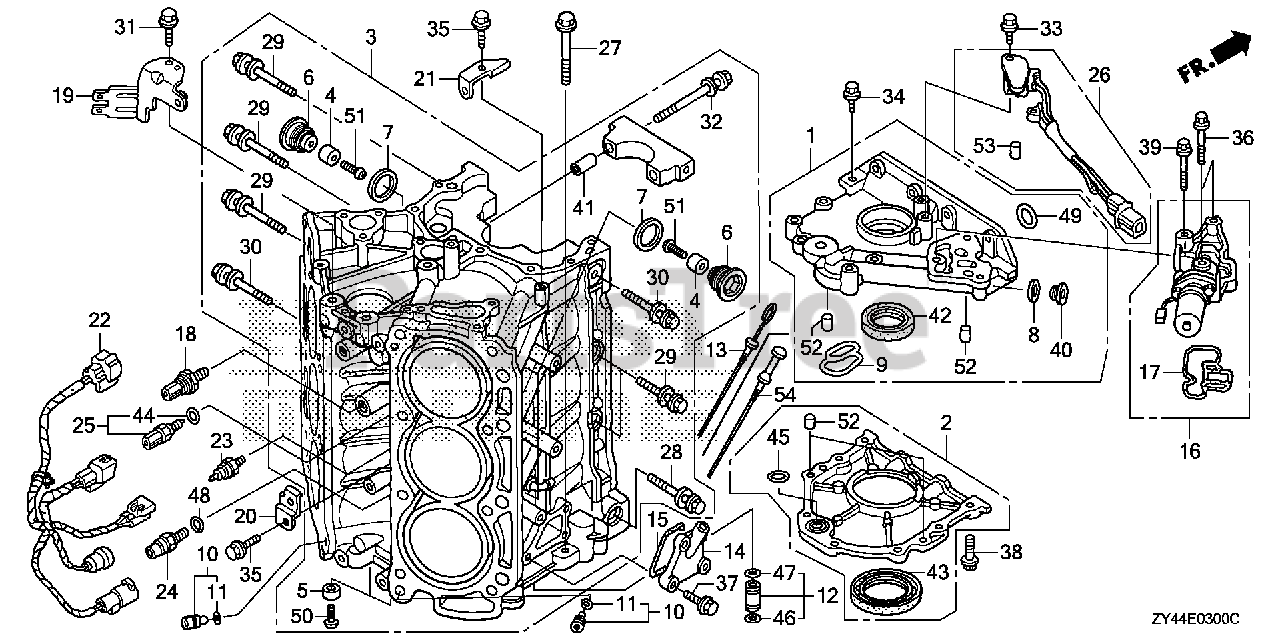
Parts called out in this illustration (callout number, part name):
1	COVER ASSY., CRANKCASE (UPPER) *NH8* (DARK GRAY)
2	CASE ASSY., OIL SEAL
3	BLOCK ASSY., CYLINDER *NH8* (DARK GRAY)
4	METAL, ANODE
5	METAL, ANODE
6	BOLT, SEALING (22MM)
7	WASHER, SEALING (22MM)
8	WASHER, SEALING (22MM)
9	GASKET, OIL HOLE
10	ORIFICE ASSY., OIL CONTROL
11	O-RING (8.8X2.4)
12	JOINT ASSY., OIL PIPE
13	DIPSTICK, OIL
14	COVER, OIL LEVEL GAUGE
15	GASKET, OIL LEVEL GAUGE
16	VALVE ASSY., SPOOL *NH8* (DARK GRAY)
17	FILTER ASSY., SPOOL VALVE
18	SENSOR, KNOCK
19	BRACKET, CONNECTOR D
20	BRACKET, CLIP B
21	BRACKET B, HARNESS CLIP
22	WIRE, SWITCH
23	SWITCH ASSY., OIL PRESSURE
24	SWITCH ASSY., OIL PRESSURE
25	SENSOR ASSY., WATER TEMPERATURE
26	SENSOR ASSY., CRANK
27	BOLT, FLANGE (12X95)
28	BOLT-WASHER (10X109)
29	BOLT-WASHER (10X60)
30	BOLT-WASHER (10X80)
31	BOLT, FLANGE (6X14) (CT200)
32	BOLT-WASHER (11X105)
33	BOLT, FLANGE (6X16)
34	BOLT, FLANGE (6X35)
35	BOLT, FLANGE (6X14)
36	BOLT, FLANGE (8X50)
37	BOLT, FLANGE (6X18)
38	BOLT, FLANGE (6X22)
39	BOLT, FLANGE (8X75)
40	BOLT, SEALING (22MM)
41	PIN, DOWEL (13X37)
42	OIL SEAL (41X66X8)
43	OIL SEAL (80X98X10) (ARAI)
44	O-RING (9.5X1.9)
45	O-RING (26.2X2.4) (YAMADA SOMBOON)
46	O-RING (18.3X3.5)
47	O-RING (16.3X3.5)
48	O-RING (13X1.5) (ARAI)
49	O-RING (25X2.4) (NOK)
50	SCREW, PAN (5X16)
51	SCREW, PAN (5X20)
52	PIN, DOWEL (6X10)
53	PIN, DOWEL (5X8)
54	DIPSTICK, OIL
